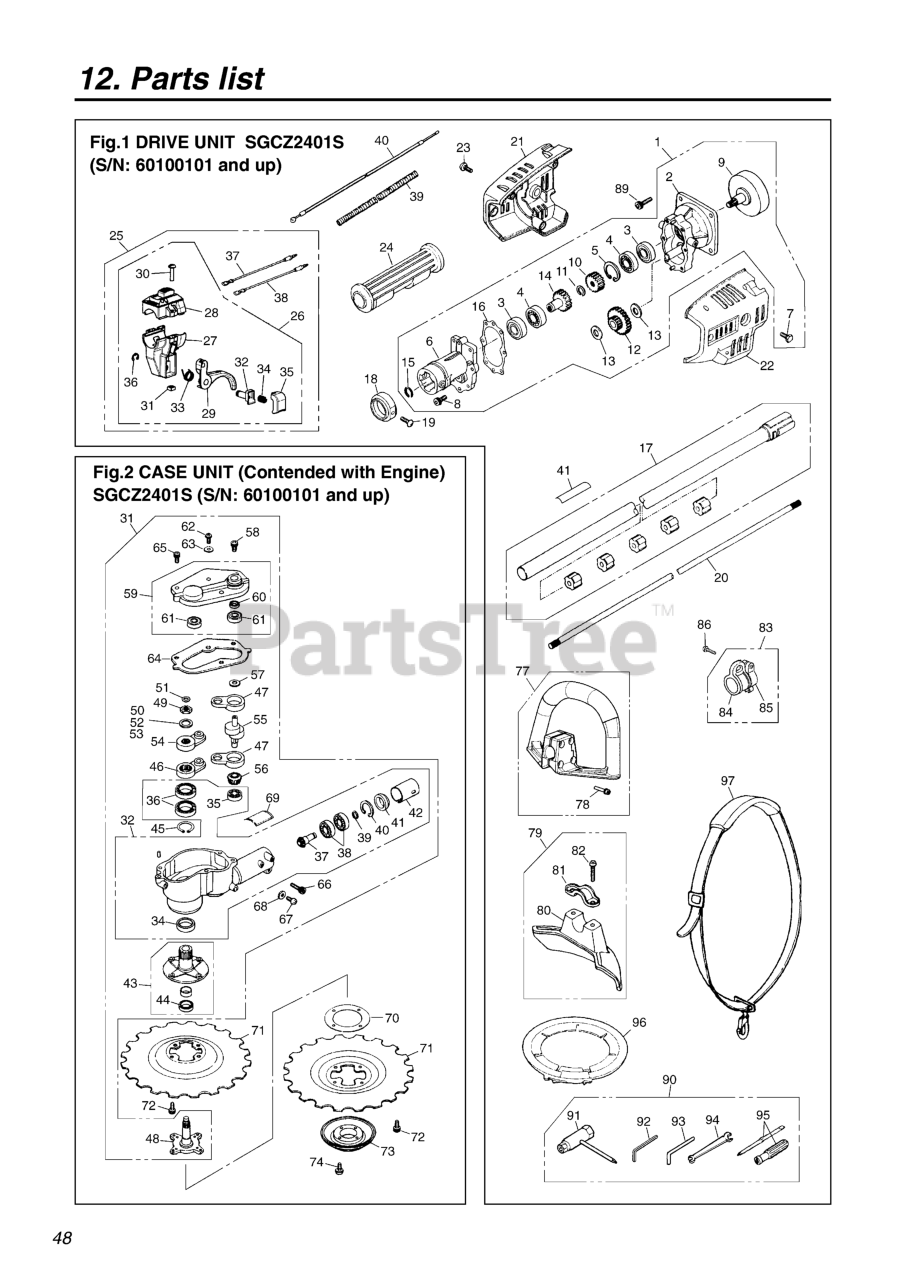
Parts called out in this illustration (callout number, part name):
1	MISSION ASSEMBLY
2	CASE, REAR COMP (RPLS -11101)
4	BEARING
5	RING, SNAP, M28 x 1.2
6	CASE, FRONT
7	BOLT, M6 x 8
8	BOLT, M5 X 20
9	DRUM
10	GEAR, PINION
11	RING, SNAP
12	GEAR (RPLS 3805-11330)
13	WASHER
14	GEAR, WHEEL
16	GASKET (RPLS 3805-11411)
17	PIPE COMP (RPLS 3805-12100)
18	CAP
19	SCREW, M5 X 10
20	SHAFT
21	COVER, RIGHT (RPLS. -11510)
22	COVER, LEFT (RPLS -11520)
24	GRIP
25	LEVER ASSY
26	LEVER
28	COVER COMP. (RP. 6110-14410-02)
29	FLEX, TRIGGER
37	CORD (A), BLACK
38	CORD (B), RED
39	TUBE (RPLS 4900-72141)
40	CABLE COMP
41	PLATE, NAME
77	HANDLE ASSY. (REPLACES -14001)
78	SCREW
79	GUARD ASSY (RPLS -24000)
80	GUARD (RPLS -24110)
81	CLAMP (REPLACES 5807-24120)
82	BOLT, M6 x 1.30
83	HANGER COMP.
86	SCREW
89	BOLT, M6 x 20
92	WRENCH (TOOL)
93	WRENCH (TOOL)
94	SPANNER, 8 X 10 (RPLS 2540- )
95	SCREWDRIVER
96	COVER (REPLACES D0041) ACC.
97	STRAP ASSY. (USE 848-JC0-3610)
A31	CUTTERCASE ASSEMBLY
A32	CUTTERCASE (RPLS -98100)
A34	SEAL, OIL
A36	BEARING
A37	PINION
A38	BEARING (RPLS T3403-13510)
A39	RING, SNAP
A40	RING, SNAP, M26 X 1.2
A41	PACKING
A42	SPACER (RPLS -13950)
A43	SHAFT, OUTER-C
A44	SEAL, OIL
A45	RING, SNAP, M20 x 1.2
A46	ARM, LOWER (RPLS -13411)
A47	CONROD (RPLS 3805-13432)
A48	SHAFT, INNER
A50	SHIM, 0.3t
A52	SHIM, 0.2T
A53	SHIM, 0.1t
A54	ARM, UPPER (RPLS -13611)
A55	CRANKSHAFT (RPLS -13710)
A56	GEAR
A57	WASHER, M8 x 1.2
A58	BOLT
A59	COVER COMP
A60	SEAL, OIL
A62	SCREW, M6 x 10
A63	WASHER, M6 x .8
A64	GASKET
A65	BOLT, M5 x 20
A66	BOLT, M6 x 1.35
A67	SCREW, M5 x 14
A68	WASHER, M5x.8(RPLS 01624-20508
A69	LABEL, CAUTION
A71	BLADE
A72	BOLT, M6 x 8
A73	STABILIZER (RPLS -15151)
A74	SCREW, M5 X 8
